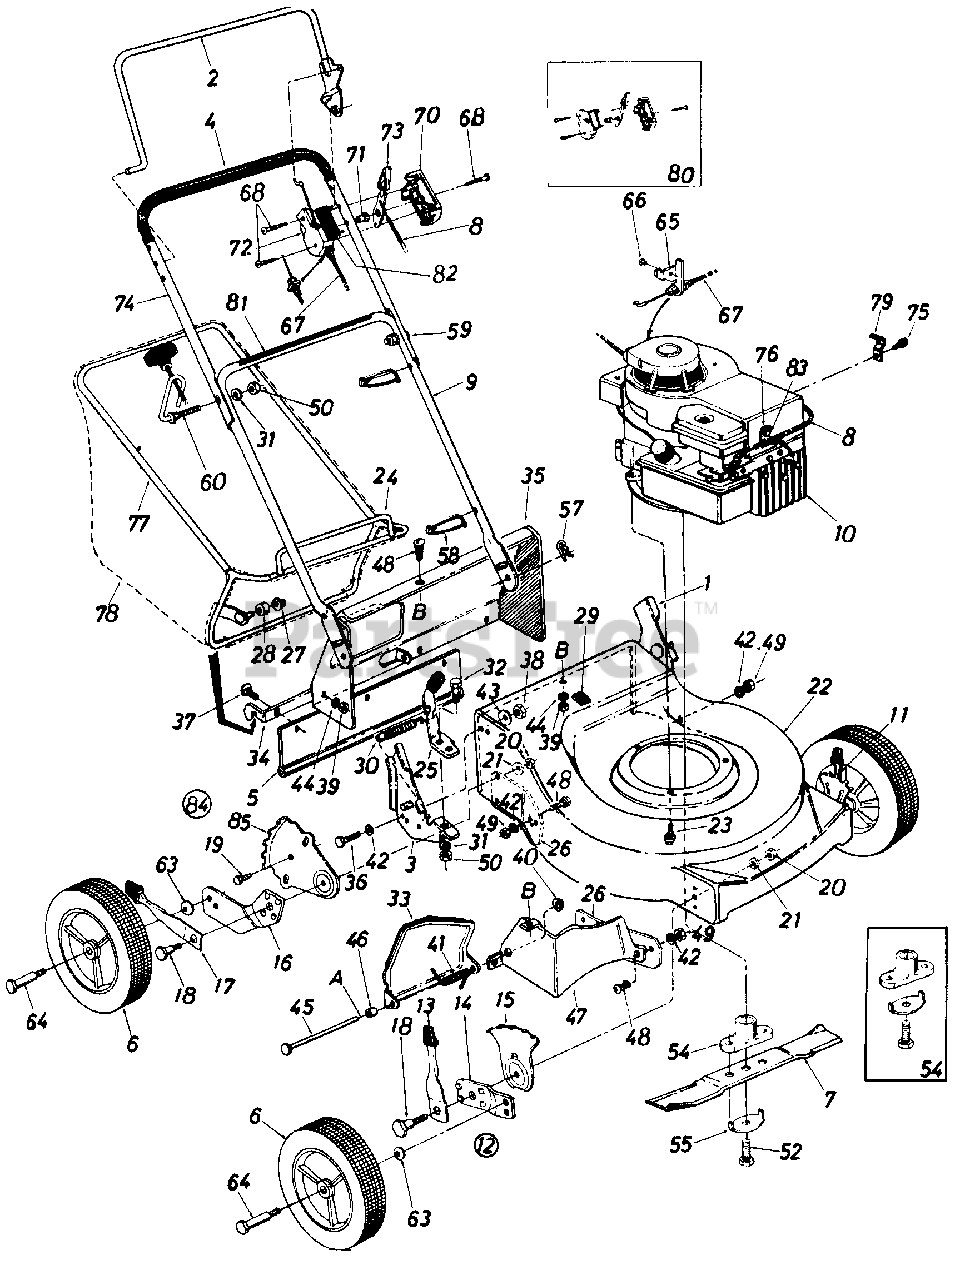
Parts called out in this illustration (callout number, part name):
1	Handle Brkt. Ass'y.-L.H.
2	Control Handle Ass'y.
3	Handle Brkt. Ass'y.-R.H.
5	Rear Flap Ass'y.
6	Wheel Ass'y.
7	21 " Blade
8	Throttle Wire-58"
9	Lower Handle
10	Engine
11	Front L.H. Height Adj. Ass'y.
12	Front R.H. Height Adj. Ass'y.
13	Spring Lever Ass'y. w/Knob
14	Front Pivot Bar
15	Front Index Plate
16	Rear Pivot Bar-R.H.
17	Spring Lever w/Knob
18	Shld. Bolt .50" Dia. x .375
19	Hex Wash. Hd. Tap Scr. 1/4 x.62" Lg.
20	Hex Nut 3/8-16 Thd.
21	Bell-Wash. .39" I.D. x .38"
26	Baffle
27	Push Nut 3/8" Rod
28	Plastic Roller
29	Plastic Plug
30	Tension Spring
31	L-Wash. 5/16" I.D.
32	Shld. Bolt .437" Dia. x .162
33	Chute Door
34	Grass Catcher Hitch Brkt.
35	Rear Deck Section
36	Hex Bolt 1/4-28 x .75" Lg.
37	Carr. Bolt 1/4-20 x .75" Lg.
38	Hex Nut 1/4-28 Thd.
39	Sems Nut 1/4-20 Thd.
40	Push Nut 1/4" Rod
41	Torsion Spring
42	L-Wash. 1/4" I.D.
43	Bell-Wash. 1/4" I.D. x .88"
44	Fl-Wash. .385" I.D. x 1.25
45	Hinge Pin
46	Spacer .262" I.D. x .58" Lg.
47	Rear Baffle
48	Carriage Bolt 1/4-20 x .50"
49	Hex Nut 1/4-20 Thd.
50	Hex Nut 5/16-18 Thd.
52	Hex Bolt 3/8-24 x 1.5" Lg. (Grade 5)
54	Blade Adapter Kit
55	Blade Bell-Wash.
56	Spark Plug Boot
57	Intern. Cot. Pin 5/16" Dia.
58	Cable Tie
59	Curved Carriage Bolt 5/16-18 x 1.38" Lg.
60	Rope Guide Bolt
63	Bell-Wash. .400" I.D. x .88" O.D. x .060
64	Axle Bolt
65	Cable Bracket
66	Pop Rivet
67	Brake Control Cable 43"
68	Truss Mach. Hd. "B" Tap Scr. #12 x 1.50" Lg.
70	Control Panel Half
71	Control Disc Pin
72	Clutch Panel Half
73	Throttle Control Lever
74	Upper Handle
75	Hex B-Tap Scr. #10 x .38" Lg.
76	Casing Clampt
77	Catcher Upper Frame
78	Grass Bag (Without Flip Top)
79	Casing Clamp
80	Control Housing Comp.
81	Instruction Label-Handle
82	Control Label-Throttle
83	Hex Wash. Hd. AB-Tap Scr. #8 x .38" Lg.
84	Rear Height Adj. Ass'y.-R.H.
85	Rear Index Plate
